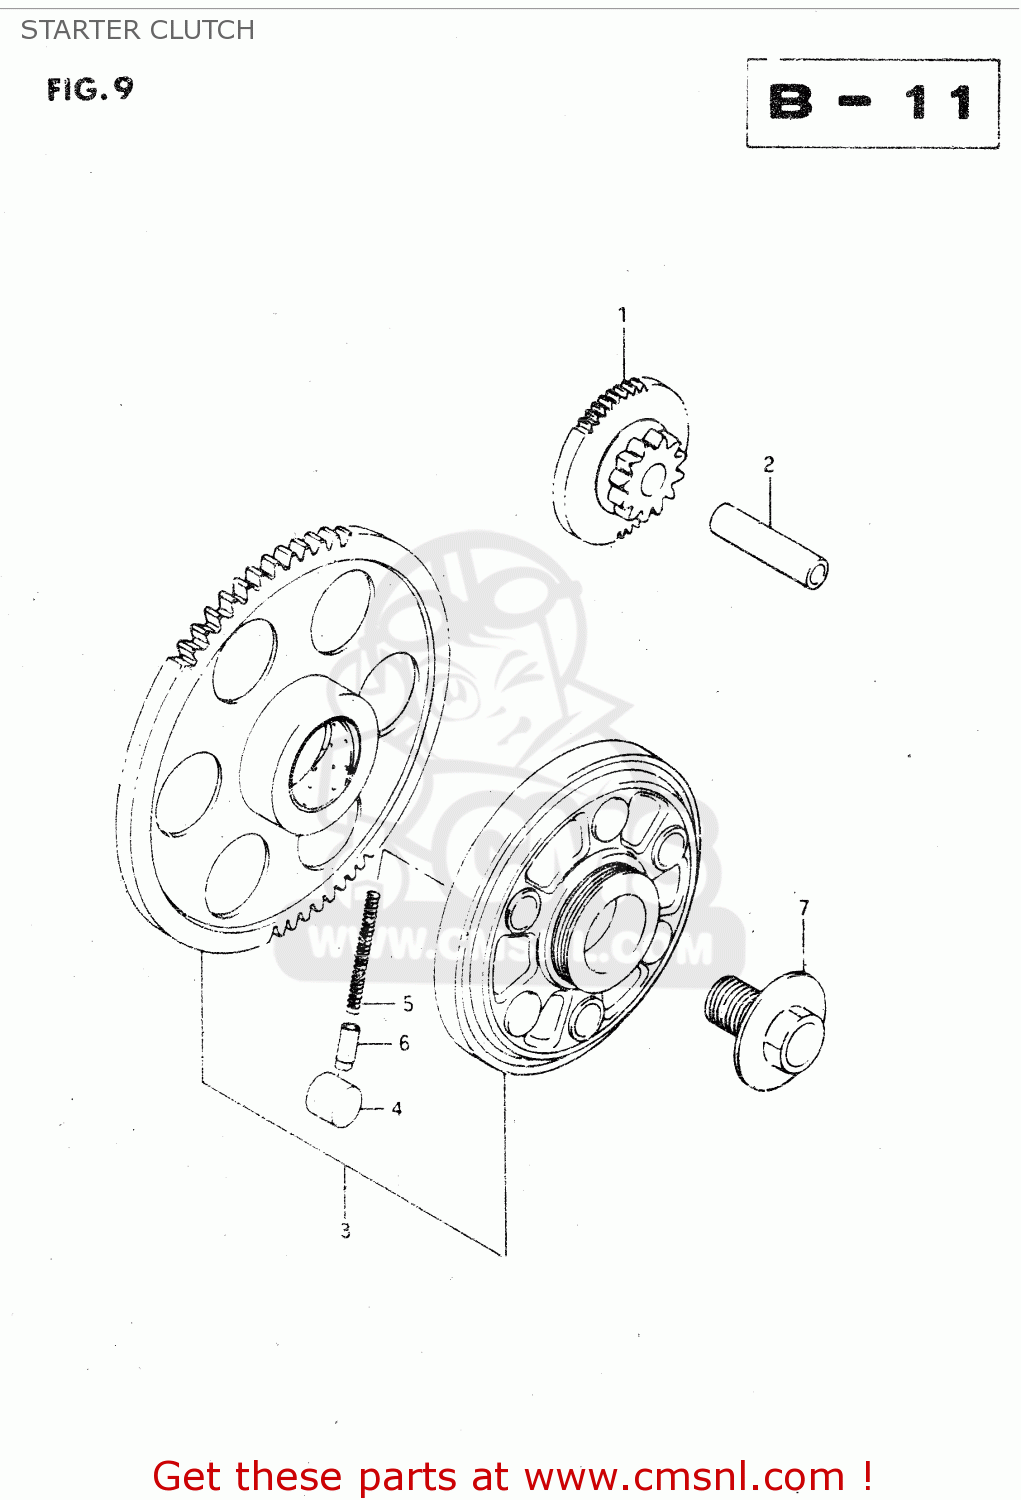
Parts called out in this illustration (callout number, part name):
1	GEAR,STARTER IDLE
2	PIN(7X11X42)
3	CLUTCH SET,STARTER
4	PIN(14X13)
5	SPRING
6	PIECE,PUSH
7	BOLT(14X21)
